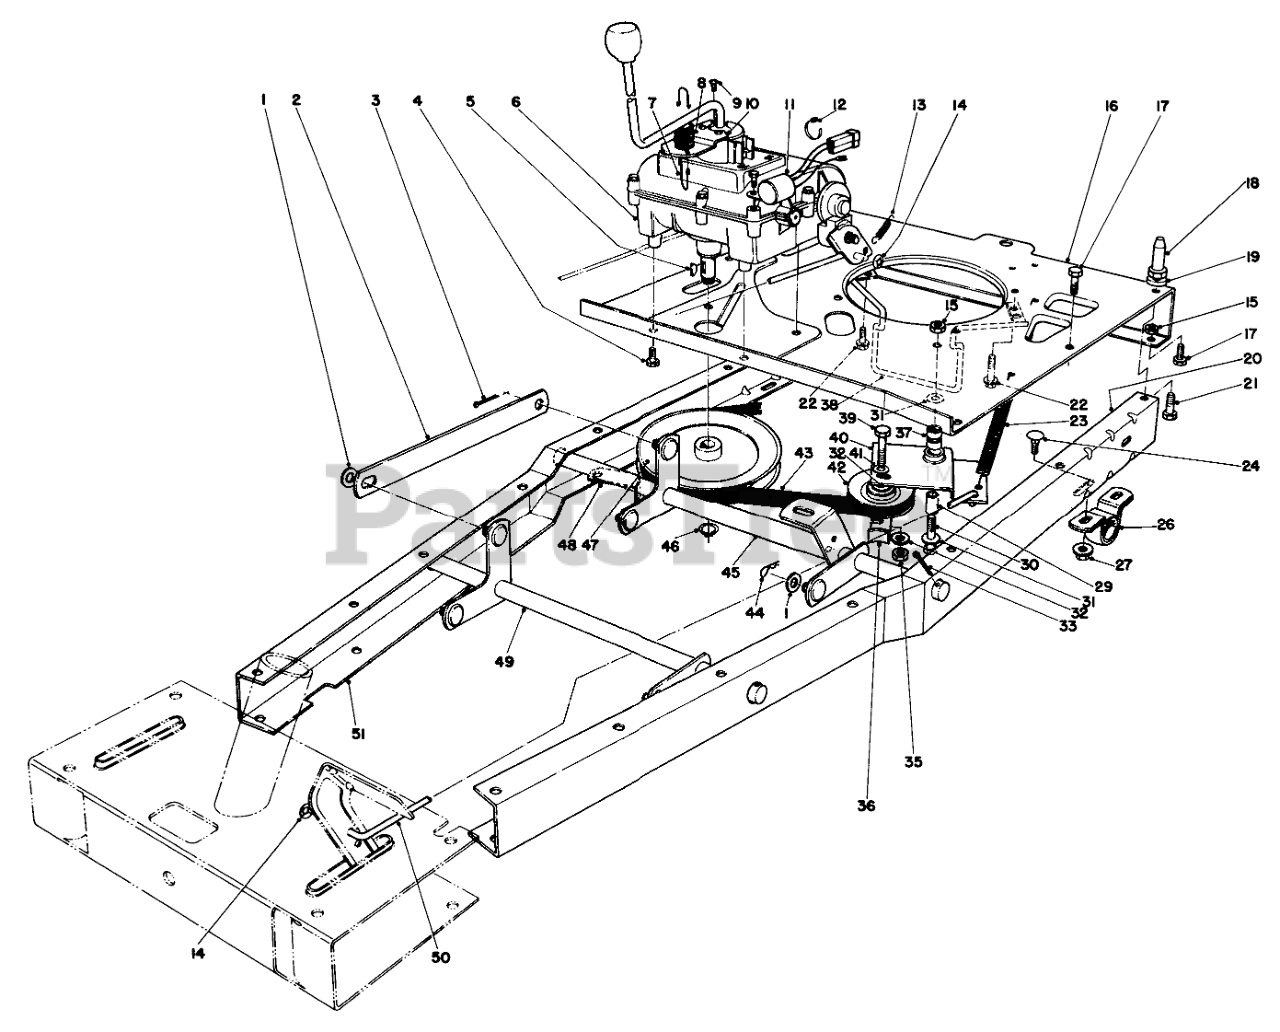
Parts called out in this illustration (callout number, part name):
1	WASHER-FLAT
2	Linkage-Height Adj.
3	PIN-COTTER
4	5/16-18 X 5/8 SEMS SC
5	KEY-WOODRUFF
6	Transmission
7	Neutral Spring Wire
8	SPRING
9	SCREW-HEAD, PAN
10	Neutral Bracket
11	Control Module
12	TIE-CABLE
13	SPRING-RETURN, BRAKE
14	PUSH ON SPEED NUT 1/4
15	NUT-LOCK, CONE
16	Engine Plate
17	SCREW-HH
18	PIN-MOUNTING, LOWER
19	SPACER-PIN, MOUNTING
20	LH FRAME CHANNEL B
21	SCREW-HH
22	SCREW-HWHTF
23	Clutch Tension Spring
24	SCREW-CARR
26	PILLOW BLOCK
27	NUT-HF
29	PIVOT SPACER
30	SCREW-HH
31	WASHER-PLAIN
32	WASHER-FLAT
33	PIN-COTTER
35	NUT-LOCK, SIDE
36	RETAINER-BELT
37	Bushing
38	Belt Guide
39	SCREW-HH
40	Traction Idler (Incl. Ref. #37)
41	WASHER-FLAT
42	PULLEY-IDLER
43	V-BELT
44	PIN-COTTER
45	HEIGHT ADJ WA (REAR)
46	RING-SNAP, EXTERNAL
47	PULLEY
48	TRANS BELT RET B
49	FRONT LIFT WA B
50	Clutch Rod
51	Frame Channel R.H.
